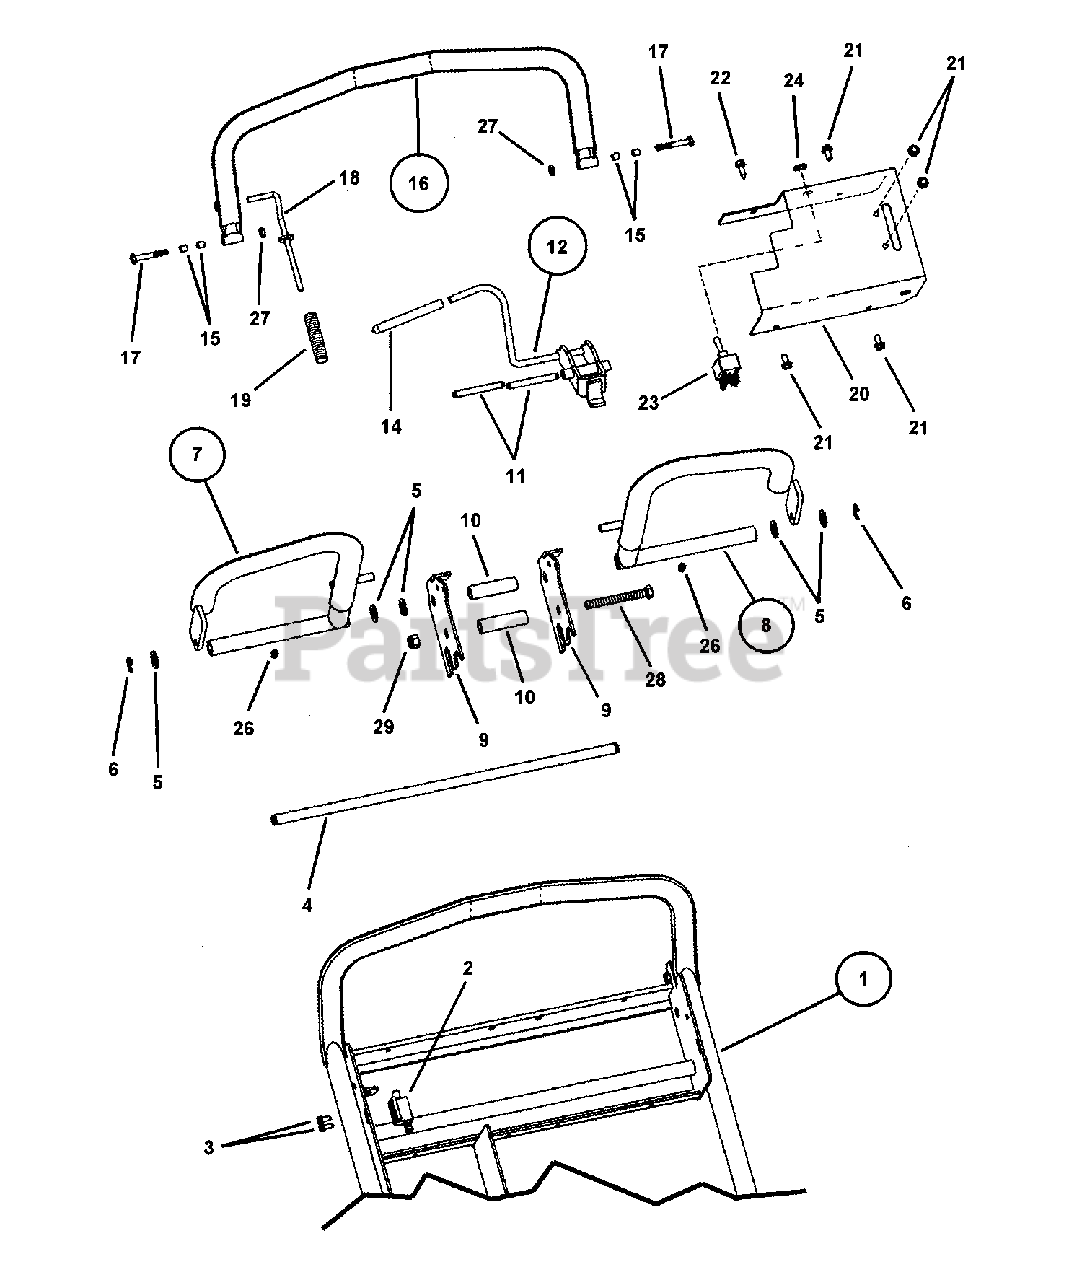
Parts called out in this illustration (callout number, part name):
1	LOOP HANDLE, Express (Weldment)
2	SWITCH, OPC (NC)
3	SCREW, #12-14 x 1/2" Hex Flange Self-Tap
4	ROD, Pivot
5	BUSHING, 1/2" Machine
6	E-RING, 1/2"
7	LEVER, Traction RH (Weldment)
8	LEVER, Traction LH (Weldment)
9	PLATE, Neutral Latch
10	SPACER, Neutral Latch
11	PIN, Shoulder
12	LATCH, Neutral (Weldment)
14	VINYL GRIP, .313 Dia. x 3-3/4" long
15	BEARING
16	BAIL, Operator Presence Control (Weldment)
17	BOLT, 1/4-20 x 1-3/4" Hex Head Cap, GR 5
18	ROD, Operator Presence Control
19	SPRING, OPC
20	PANEL, Console LH
21	SCREW, 1/4-20 x 1/2" Hex Washer Self-Tap
22	SCREW, 1/4-20 x 3/4" Hex Washer Self-Tap
23	SWITCH, Toggle (Indak H671A)
24	NUT, 1/2-27 (Special)
26	GREASE FITTING (1/2-28 thread)
27	NUT, 1/4-20 Hex Jam
28	SCREW, 3/8-16 x 3-1/4" Hex Head Cap, GR 5
29	NUT, 3/8-16 HEX NYLON LOCK
